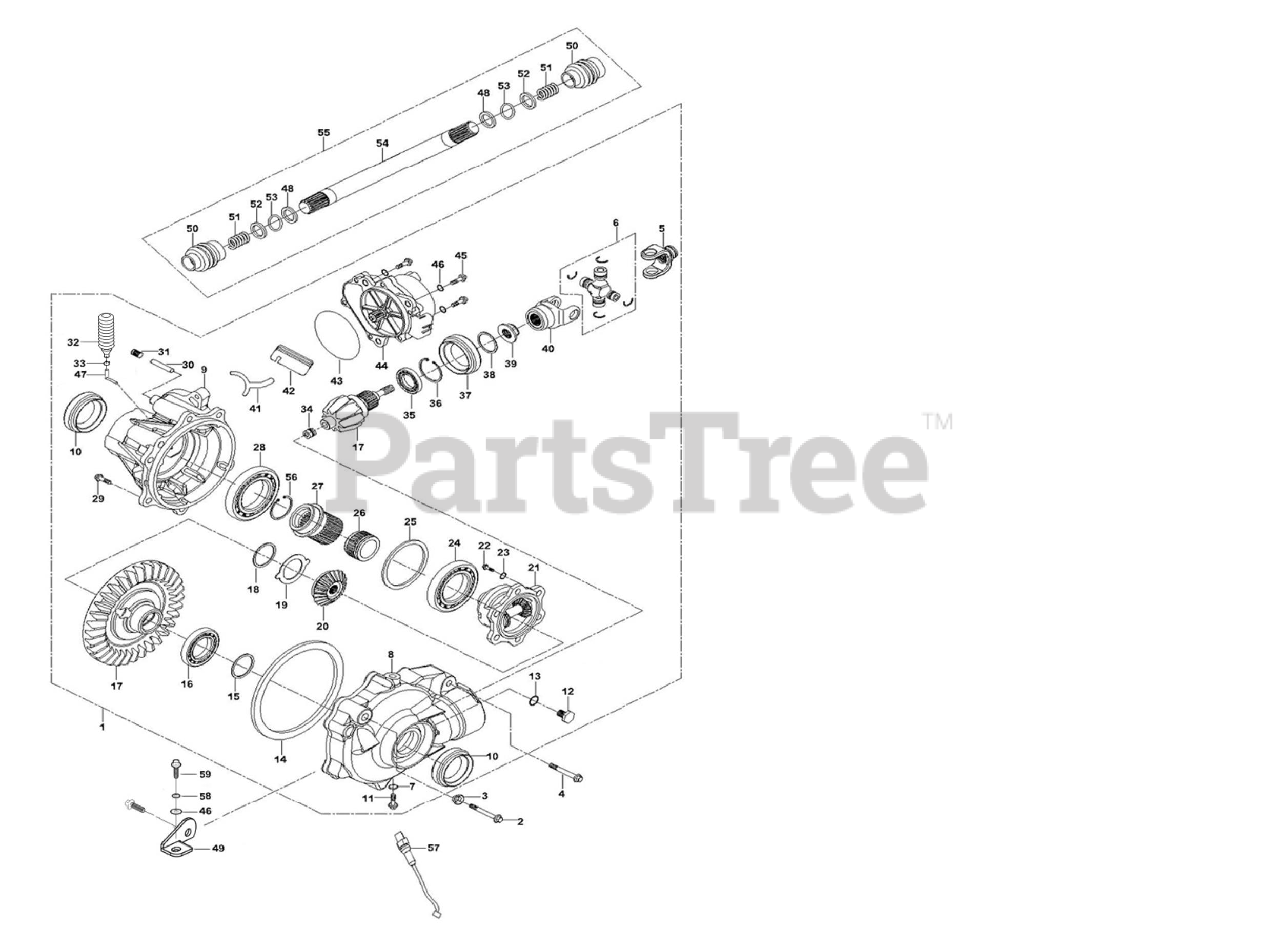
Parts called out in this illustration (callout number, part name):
1	FRONT DIFFERENTTIAL ASSEMBLY
2	BOLT HExAGON FLANGE HEAD M10x1.25-145
3	LOCK NUT M10x1.25
4	Hexagon Flange Bolt M10x30
6	Criss-Cross Shaft
7	O-RING 1.5x9
8	GEARCASE LEFT
9	Front Diff. Cover
10	SEAL 24x38x8
11	Flange bolt M10x1.25x16
12	DRAIN PLUG M14x1.5-10
13	O-RING 12.5x1.5
14	O-RING 140x2.65
15	Adjusting washer 50x 61.5x0.1
16	Bearing 6007
18	Adjusting washer 40x 57x0.1
19	LOCK WASHER
21	DIFFERENTIAL CASE
22	Hexagon Bolt M10x1.25x16
24	BEARING 61912
25	Adjusting washer 71x 83x0.1
26	Shaft sleeve
28	BEARING 16007
29	Flange bolt M8x25
30	PIN - ROLLER 5x75
31	BOLT STOPPER M8x10
33	Spring Clamp E
34	NEEDLE BEARING HK1512
35	Bearing 6007
37	SEAL 48x65x9
38	O-RING 14x7
39	LOCK NUT M14x1.5
41	FORK SHAFT
43	O-RING 81x2
44	GEAR MOTOR
45	Hexagon Socket Cap Screw M8x20
47	Front diff air fitting
49	FRONT AxLE MOUNTING PLATE
50	Rear axle rubber boot C
51	Rear axle Spring B
54	FRONT DRIVE SHAFT
55	FRONT DRIVE SHAFT ASSEMBLY
57	SPEED SENSOR
58	Spring Washer-8
59	Hexagon Flange Bolt M8x20
